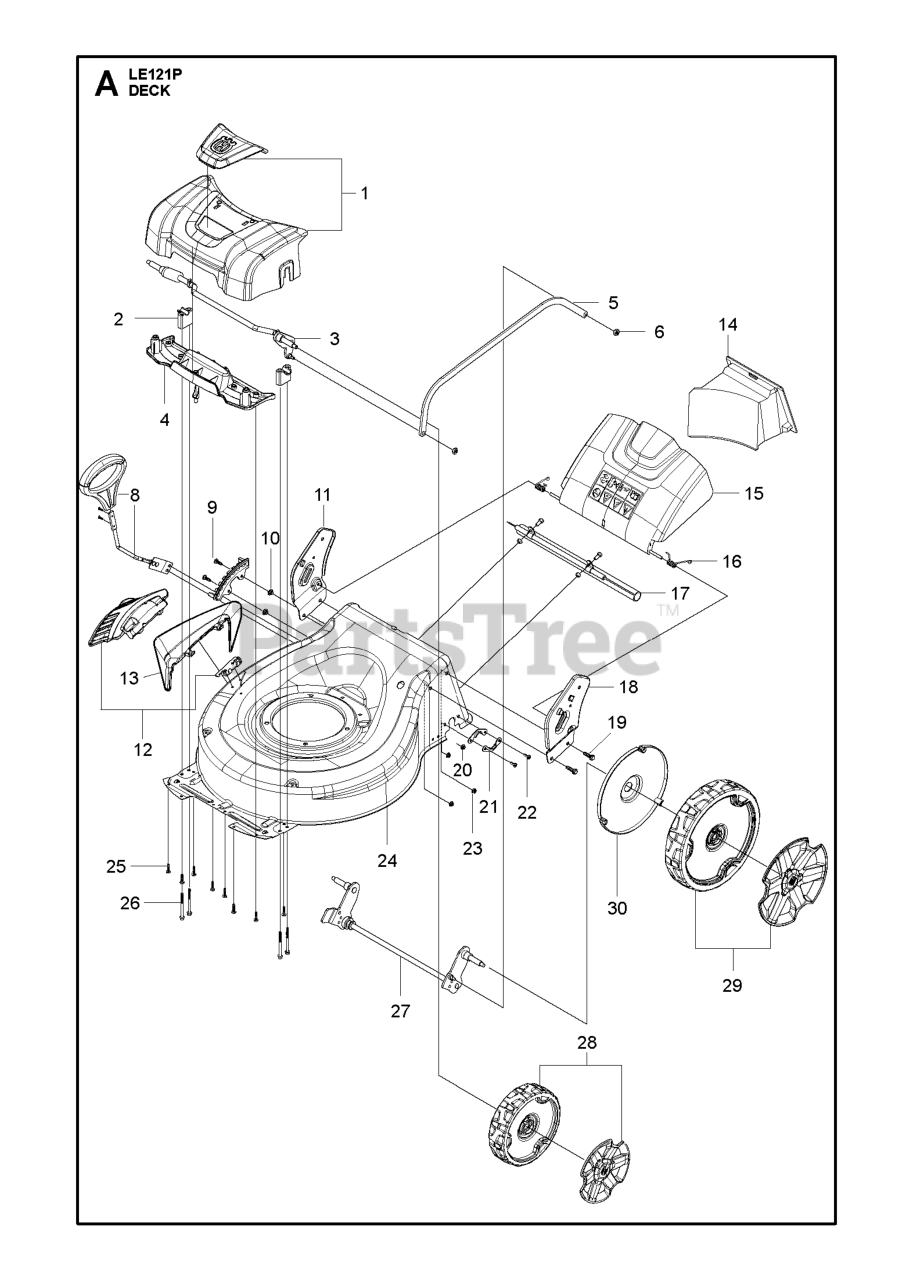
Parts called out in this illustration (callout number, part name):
1	FRONT COVER ASSY FRONT COVER U
2	BRACKET FRONT AXLE
3	WHEEL AXLE SUSPENSION FRONT
4	COVER FRONT COVER LOW
5	ROD SUSPENSION
6	LOCKING BOLT M6,GB889.1 #26800
8	LEVER ASSY HEIGHT ADJUSTMENT H
9	SCREW MACHINED DAYE# A26800201
10	LOCK NUT M6 LOCKING HEX FLANGE
11	HANDLE SUPPORT RIGHT
12	HATCH SIDE DISCHARGE
13	DEFLECTOR SIDE DISCHARGE
14	MULCH PLUG
15	HATCH REAR DISCHARGE
16	SPRING REAR DISCHARGE HATCH
17	FLAP REAR TAIL
18	HANDLE SUPPORT LEFT
19	BOLT M8*16 #26800606401
20	LOCK NUT M6 LOCKING HEX FLANGE
21	BRACKET REAR ASSY LE121P
22	SCREW M6*16 #26800204601
23	LOCKING BOLT M8,GB6187.1 #2680
24	CHASSIS DECK ASSY
25	SCREW SELF TAPPING DAYE# A2680
26	SCREW HEX FLANGE DAYE# A268006
27	WHEEL AXLE SUSPENSION REAR LE1
28	WHEEL ASSY FRONT LE121P / LE22
29	WHEEL ASSY REAR LE121P
30	DUST COVER 20 INCH MOWER
